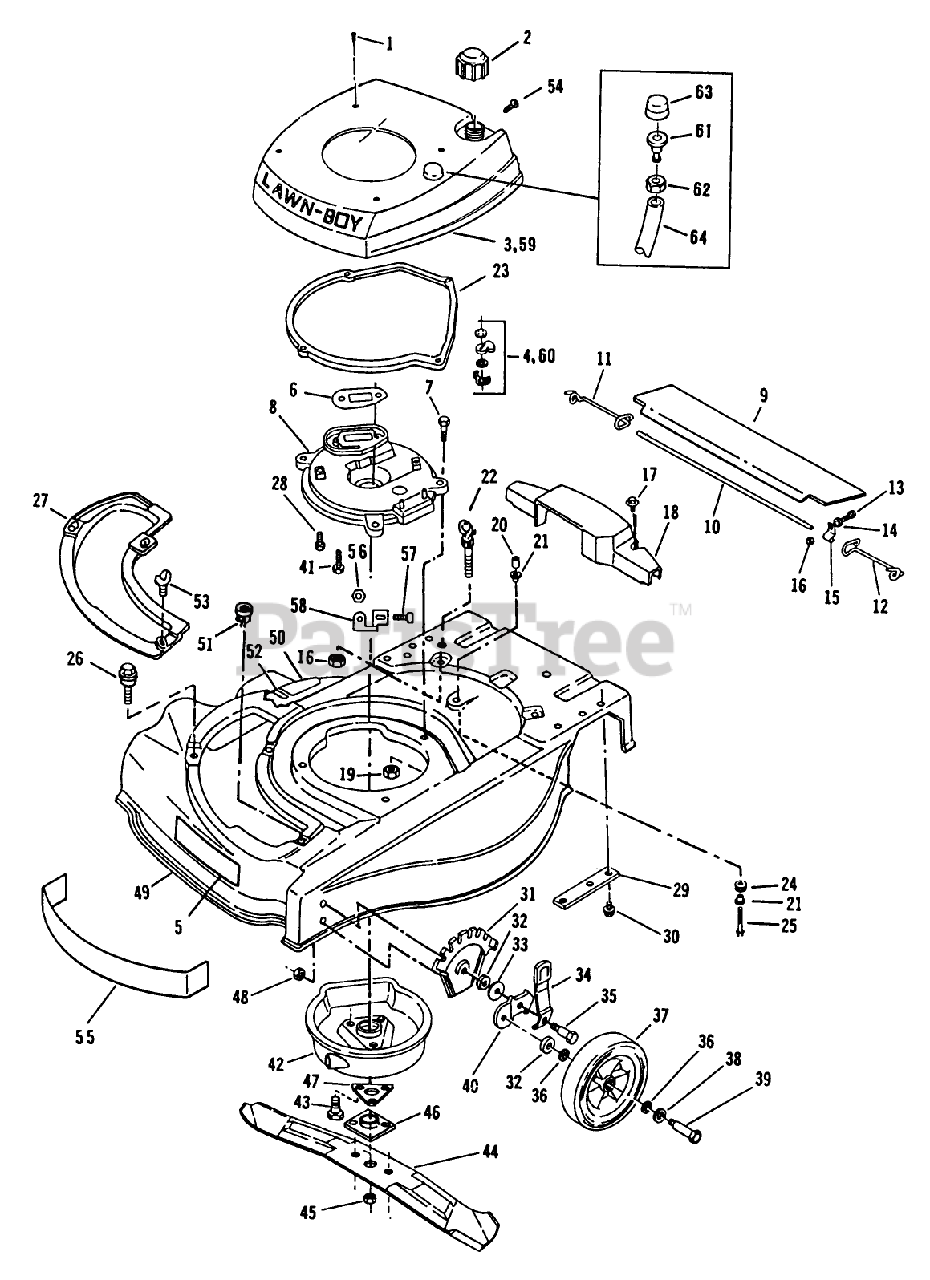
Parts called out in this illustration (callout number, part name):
1	SCREW LAWRENCE
2	FUEL CAP & INSERT
7	SCREW-HH
8	PLATE,MUFFLER F
10	ROD T/SHIELD ADV WIRE
11	SPRING;TRAILING SHIELD RH
12	SPRIG T/SHLD ASOC
14	Washer-Trailing Shield
15	CLAMP ROD KMC
16	LOCKNUT E
17	SCREW SEMS TRM HEX HD
19	NUT-LOCK F
20	SPACER
21	SPACER ECK PRES
22	BOLT-EYE
30	SCREW
31	PLATE HGT ADJ TRO
32	WASHER WROUGHT
33	WASHER
34	KNOB&SPRING FORMCO
35	BOLT
36	WASHER
37	WHEEL & TIRE KIT
38	SPACER
39	BOLT WHEEL
41	SCREW V
43	SCREW
45	NUT-BLADE
46	PLATE AND COLLAR ASM
47	SUPPORT F
48	LOCKNUT
53	WING SCREW LAWRE
54	SCREW S
56	LOCKNUT E
62	LOCKNUT S
63	P-BULB LAV-RUB
64	TUBING-PRIMER POLY
